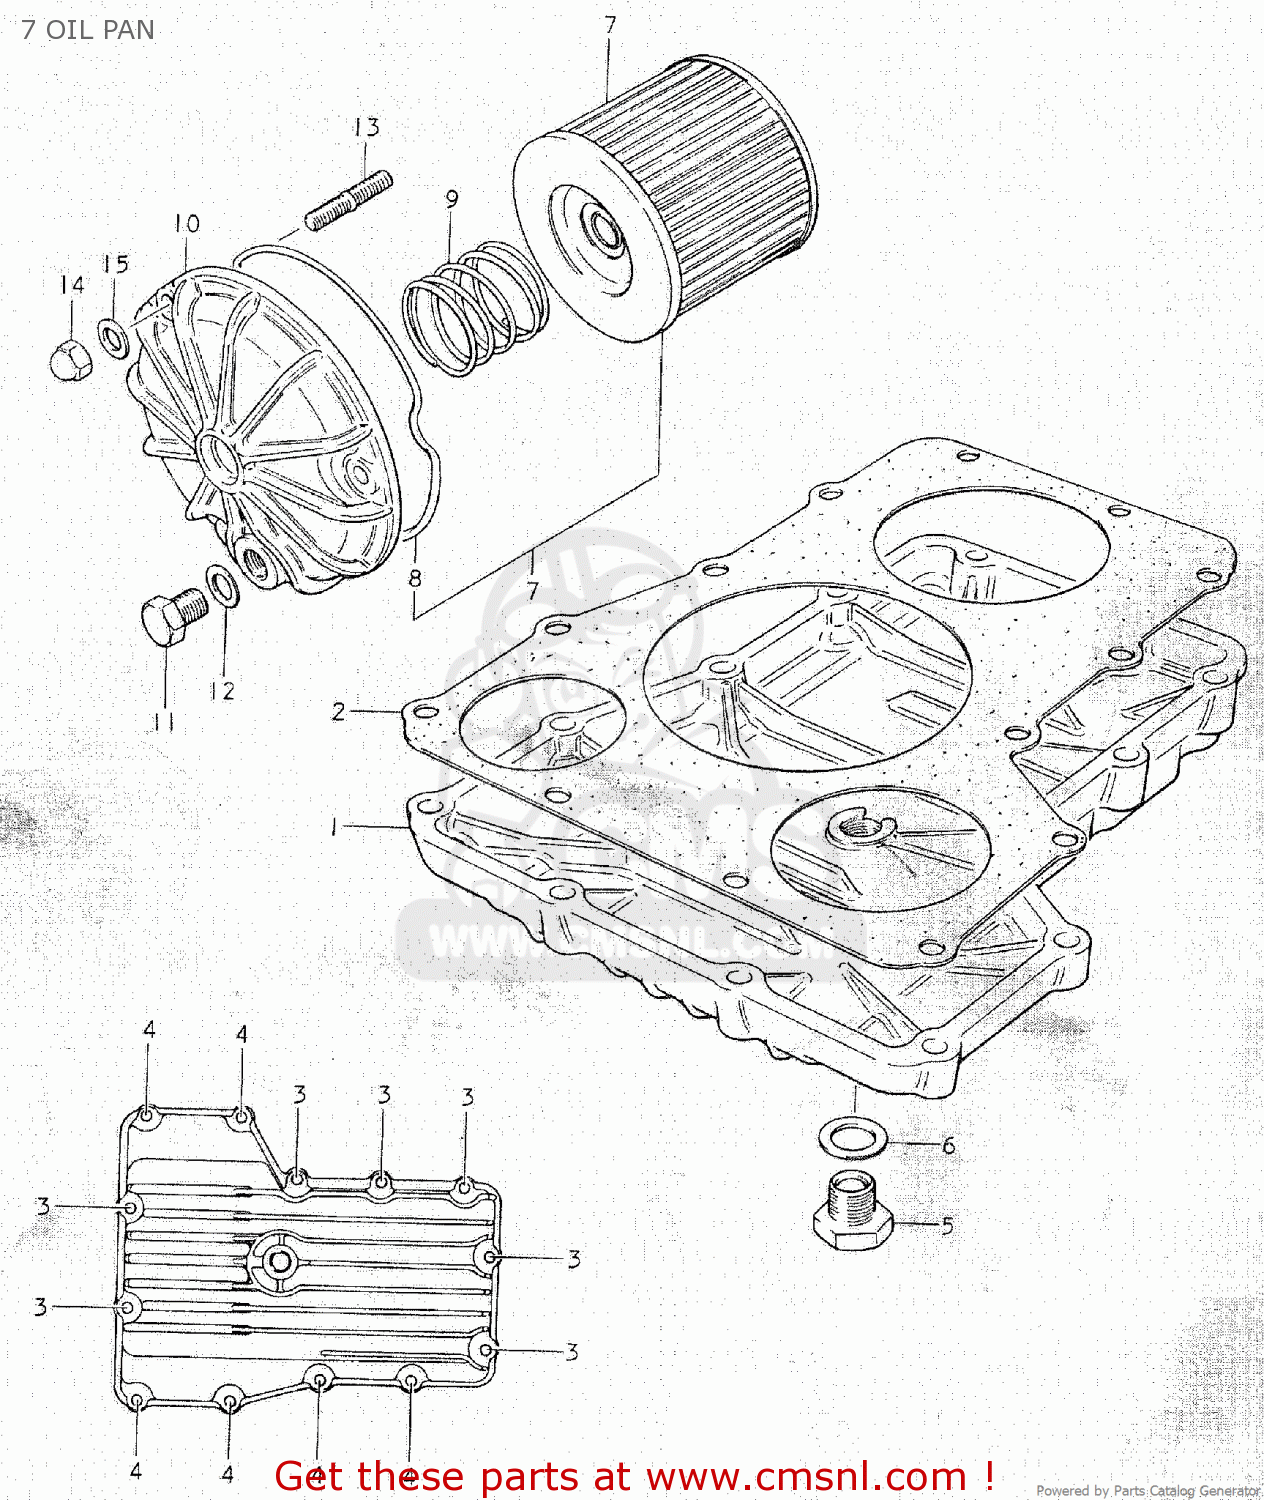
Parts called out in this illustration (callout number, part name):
1	PAN,OIL
2	GASKET,OIL PAN (MCA)
3	BOLT
4	BOLT
5	PLUG
6	GASKET(14X19.2X2) (NAS)
7	ENGINE OIL FILTER SET
8	O RING,OIL FILTER CHAMBER CAP
9	SPRING
10	CAP,OIL FILTER
11	PLUG
12	GASKET(10X14X3.6) (NAS)
13	STUD 6X20
14	NUT
15	WASHER 6MM
